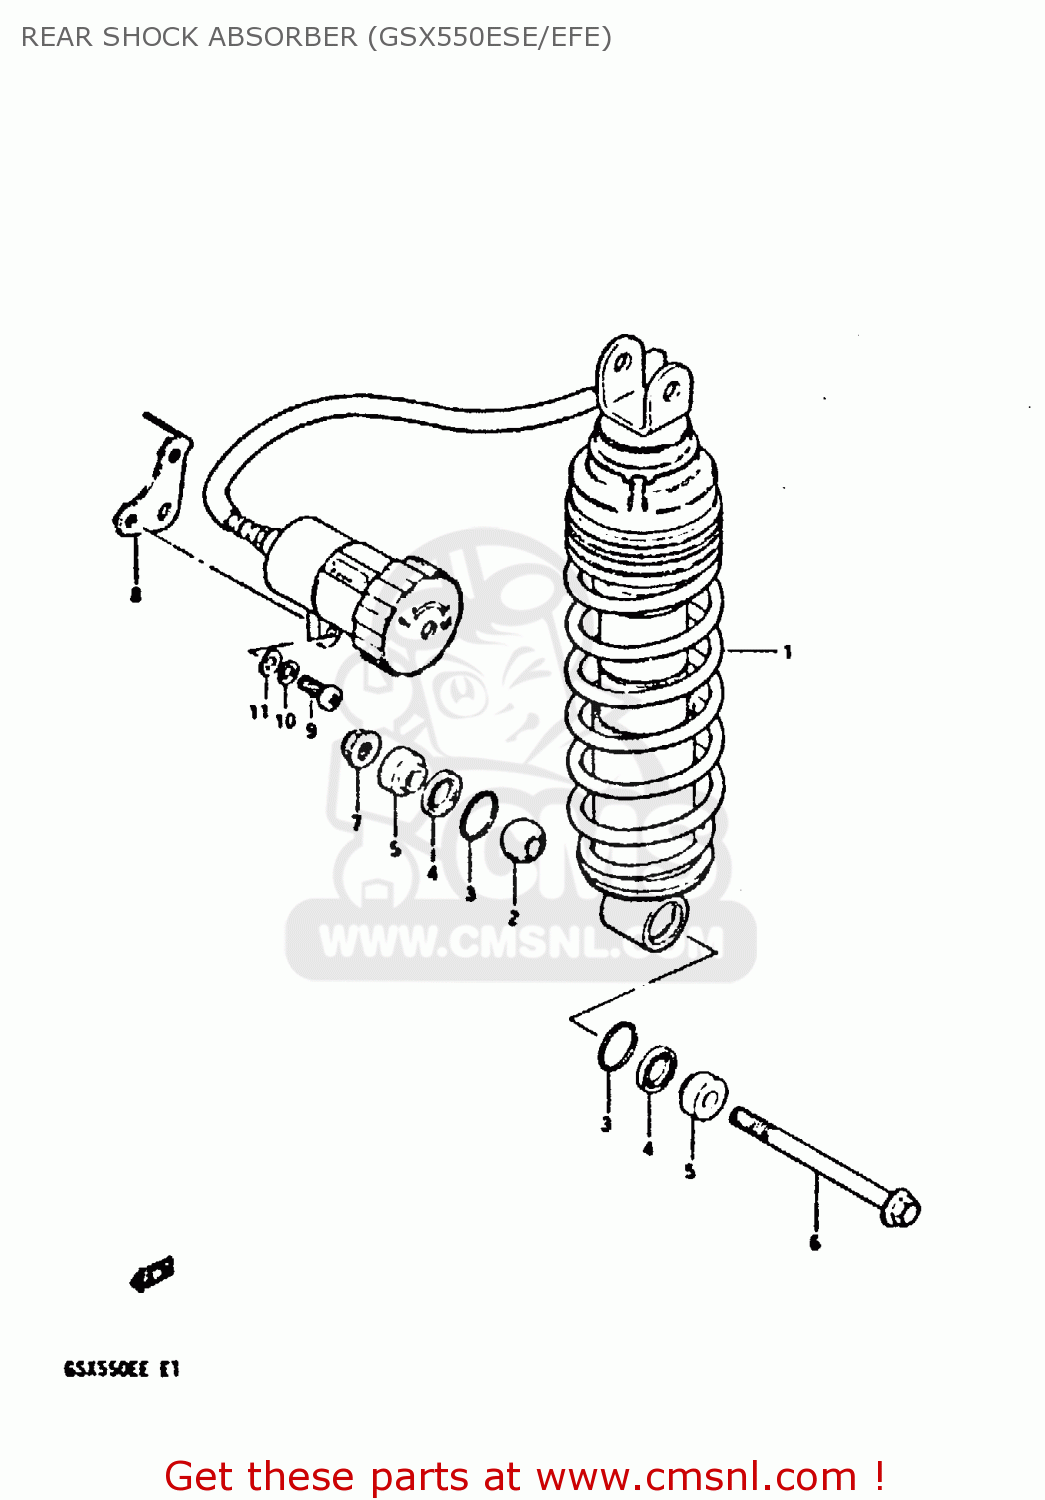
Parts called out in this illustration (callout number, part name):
1	SHOCK ABSORBER, REAR
2	BEARING,REAR SHOCK ABSORBER
3	RING
4	SEAL,DUST
5	COLLAR
6	BOLT(10X115)
7	NUT
8	BRACKET,RESERVOIR TANK
9	SCREW
10	LOCK WASHER
11	WASHER
